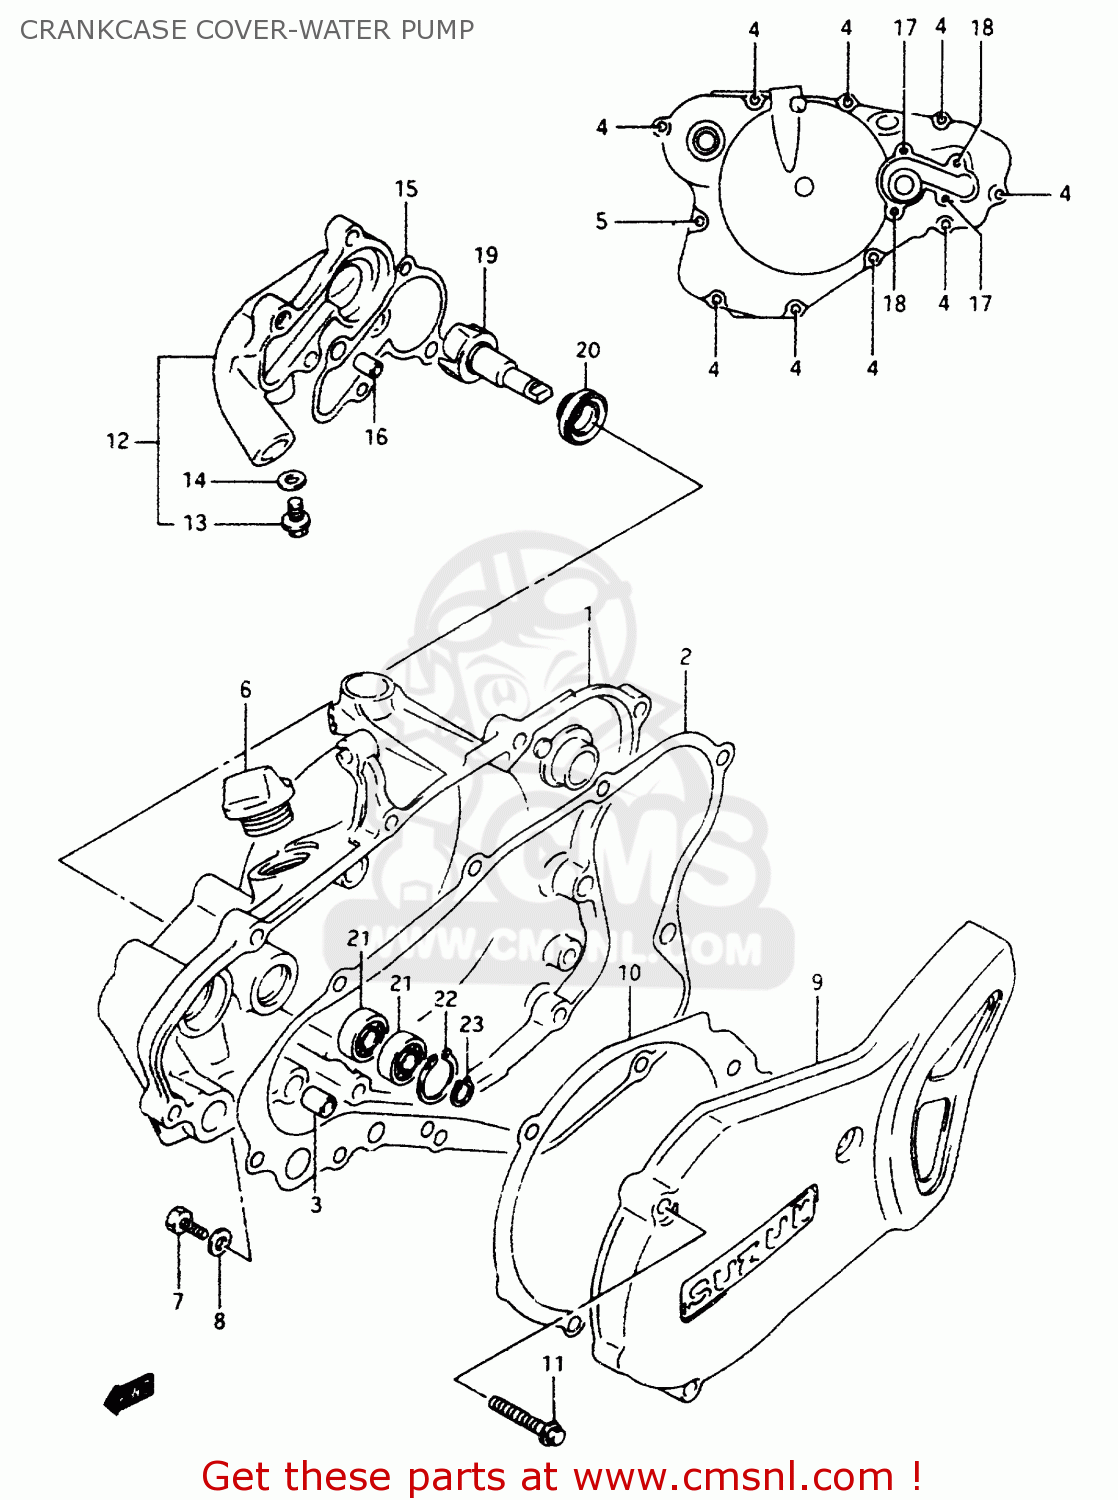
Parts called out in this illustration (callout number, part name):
1	COVER,CLUTCH
2	GASKET,CLUTCH COVER (NAS)
3	PIN
4	SCREW
5	BOLT
6	PLUG SET
7	SCREW(6X10)
8	GASKET(6.2X11X1).2 (NAS)
9	COVER,MAGNETO
10	GASKET,MAGNETO COVER (NAS)
11	SCREW
12	CASE,WATER PUMP
13	BOLT
14	WASHER
15	GASKET,WATER PUMP CASE (NAS)
16	PIN
17	SCREW
18	BOLT,G/S SWITC
19	IMPELLER,WATER PUMP
20	SEAL,WATER PUMP OIL
21	BEARING
22	CIRCLIP
23	CIRCLIP
